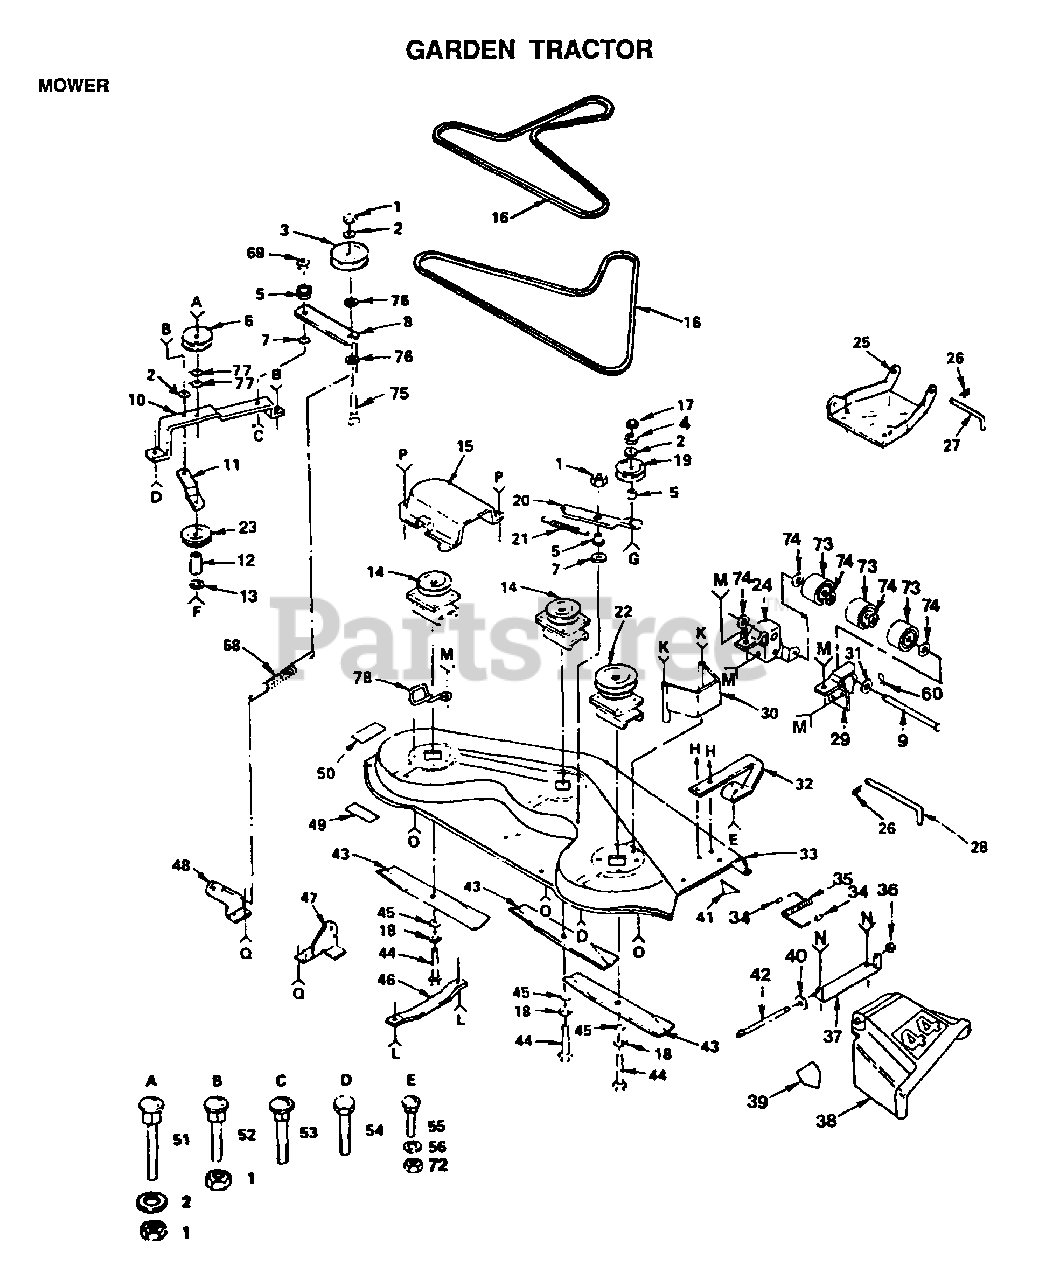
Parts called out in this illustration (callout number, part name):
2	WASHER
3	PULLEY IDLER
4	LOCKWASHER
5	SPACER RETAINER
6	IDLER-INSIDE T
7	"WASHER, WEAR LT"
8	ARM IDLER
9	PIVOT PIN T
10	"SUPPORT YT, BAR"
11	BRACE-IDLER YT
12	SPACER
13	WASHER
15	GUARD YT
16	BELT-V.79.1.MWR
17	NUT.HEX.3/8-16UNC
19	IDLER.FLAT.GTV
20	ARM-IDLER YT
22	JACKSHAFT
23	IDLER-FLAT T
24	BRACKET LH YTH
25	LINK.PARALLEL
26	SPRING.RETAINER
27	"ROD, FRT. PARAL T"
28	HINGE PIN T
29	BRACKET RH YTH
30	GUARD BELT HYT
34	CAP-SLEEVE LT
36	NUT PUSH M
38	DEFLECTOR SHIELD
39	DECAL WARNING
40	WASHER
42	ROD-HINGE T
44	BOLT.3/8-24X1-1/2
45	WASHER
49	DECAL HYT
50	DECAL-INST YT
51	BOLT
53	BOLT
55	BOLT
56	WASHER
60	COTTER PIN
68	"SPRING.EXT.8.5"""
69	LOCKNUT
73	ROLLER T
74	WASHER T
75	BOLT
76	WASHER
77	WASHER
78	BELT RETIANER
